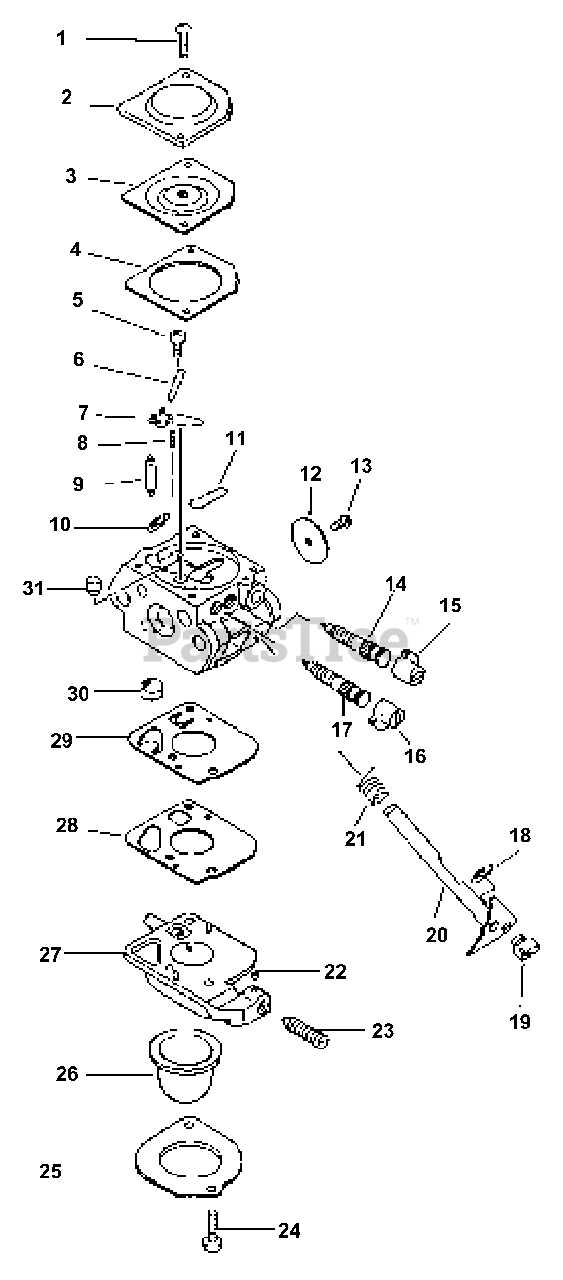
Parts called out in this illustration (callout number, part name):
2	COVER, METERING DIAPHRAGM
3	DIAPHRAGM, METERING
4	GASKET, METERING
6	PIN, METERING LEVER
7	LEVER, METERING
8	SPRING, METERING LEVER
9	VALVE, INLET NEEDLE
11	PLUG, WELCH
12	VALVE, THROTTLE
14	NEEDLE, LOW SPEED
15	CAP, LIMITER - WHITE
16	CAP, LIMITER - RED
17	NEEDLE, HIGH SPEED
20	SHAFT, THROTTLE
21	SPRING, THROTTLE RETURN
22	PIECE, FRICTION
23	SCREW, IDLE ADJUST
25	RETAINER
26	BULB, PURGE
27	BODY ASSY, PURGE
28	GASKET, PUMP
29	DIAPHRAGM, PUMP
30	STRAINER
31	NOZZLE, CHECK VALVE
